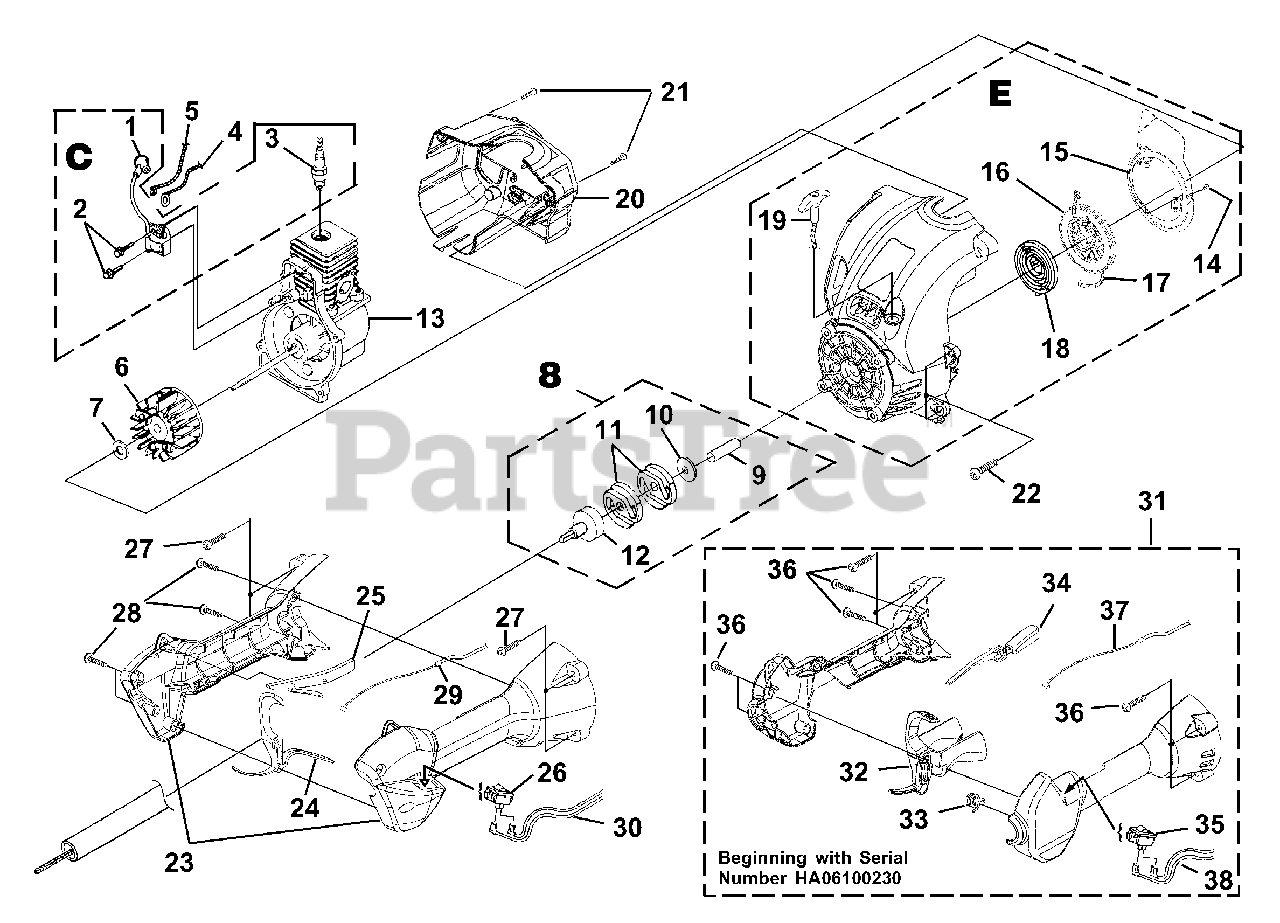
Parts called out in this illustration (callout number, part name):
1	TERMINAL & COVER
2	SCREW-Taptite (8-32 X 1")
3	SPARK PLUG
4	LEAD-Electrical
5	LEAD-Electrical
6	ROTOR KIT
7	WASHER-Flat
8	CLUTCH AND DRUM KIT
9	SPACER
10	WASHER-Flat
11	CLUTCH
12	CONNECTOR AND DRUM
13	SHORT BLOCK
14	SCREW-Thread Form (8-16 X 1/2")
15	BAFFLE-Air
16	PULLEY-Starter
17	ROPE-Starter (42")
18	SPRING & CONTAINER
19	GRIP-Starter (Yellow)
20	HOUSING-Rear Kit
21	SCREW-Plastite (10-14 X 7/8")
22	SCREW-Taptite (10-24 X 3/4")
23	CONTROL HANDLE ASSY.
24	TRIGGER-Throttle
25	THROTTLE INTERLOCK
26	SWITCH
27	SCREW-Taptite (10-14 X 7/8")
28	SCREW-Taptite (10-24 X 3/4")
29	CABLE-Throttle
30	LEAD-Electrical
31	CONTROL HANDLE ASSY.
32	TRIGGER-Throttle
33	SPRING
34	THROTTLE INTERLOCK
35	SWITCH
36	SCREW-Taptite (10-14 X 1")
37	CABLE-Throttle
38	LEAD-Electrical
C	IGNITION KIT
E	COMPLETE STARTER ASSEMBLY
